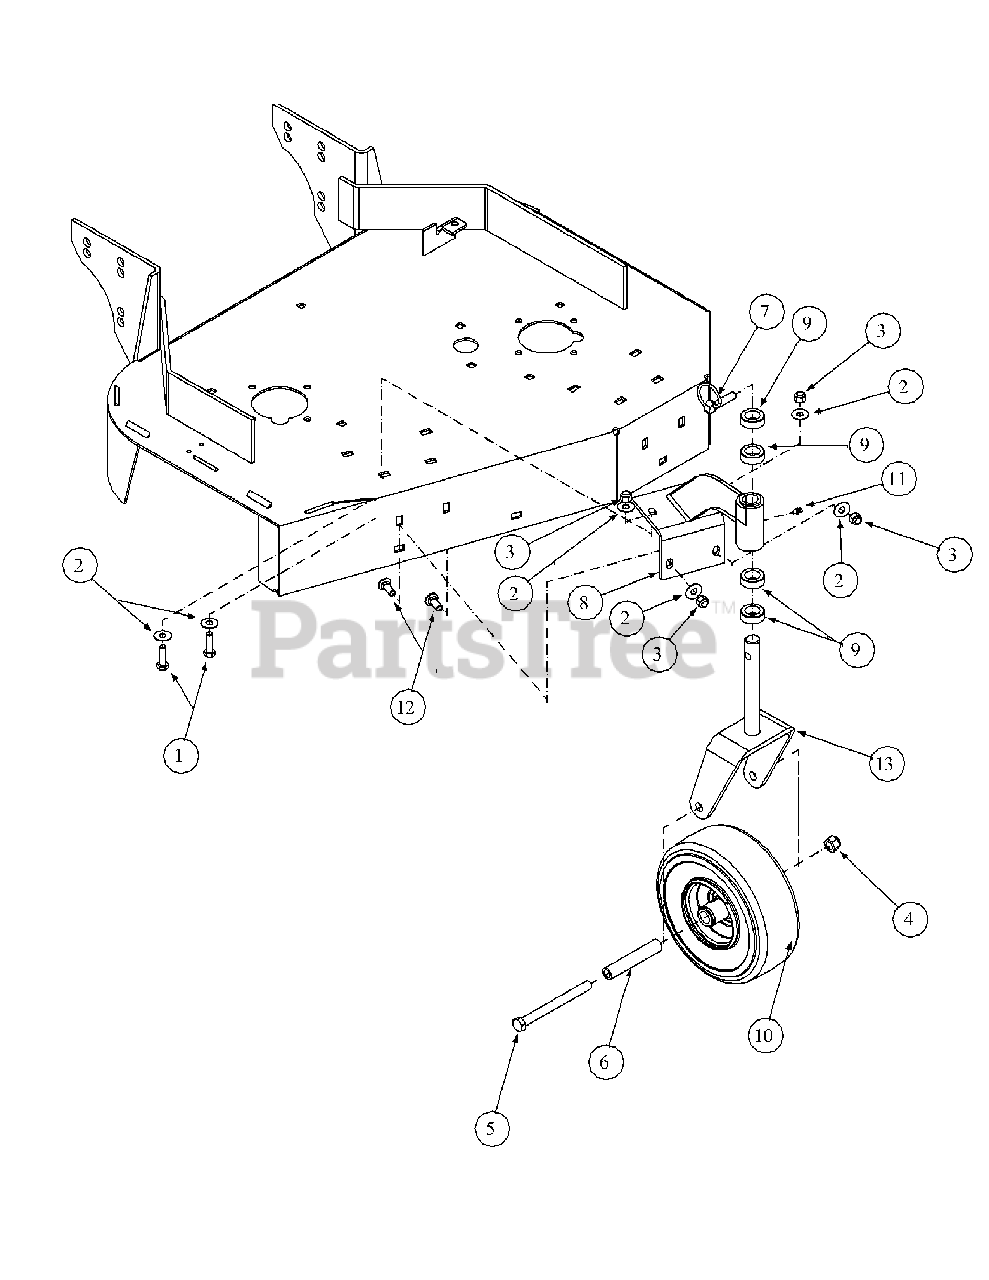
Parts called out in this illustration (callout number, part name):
1	Hex Cap Screw, 3/8-16 x 1-1/4
2	Flat Washer, 3/8 Zinc
3	Lock Nut, Nylon Insert, 3/8-16
4	Lock Nut, Nylon Insert, 1/2-13
5	Hex Cap Screw, 1/2-20, 5.50
6	Spacer Wheel
7	Klik Pin, 1.75
8	Caster Bracket Assembly
9	Spacer, Caster
10	Wheel Assembly, 9.0 x 3.50-4
11	Grease Fitting, 1/4-28 x 3/16
12	Carriage Bolt, 3/8-16 x 1
13	Caster Yoke Assembly, Weldment
